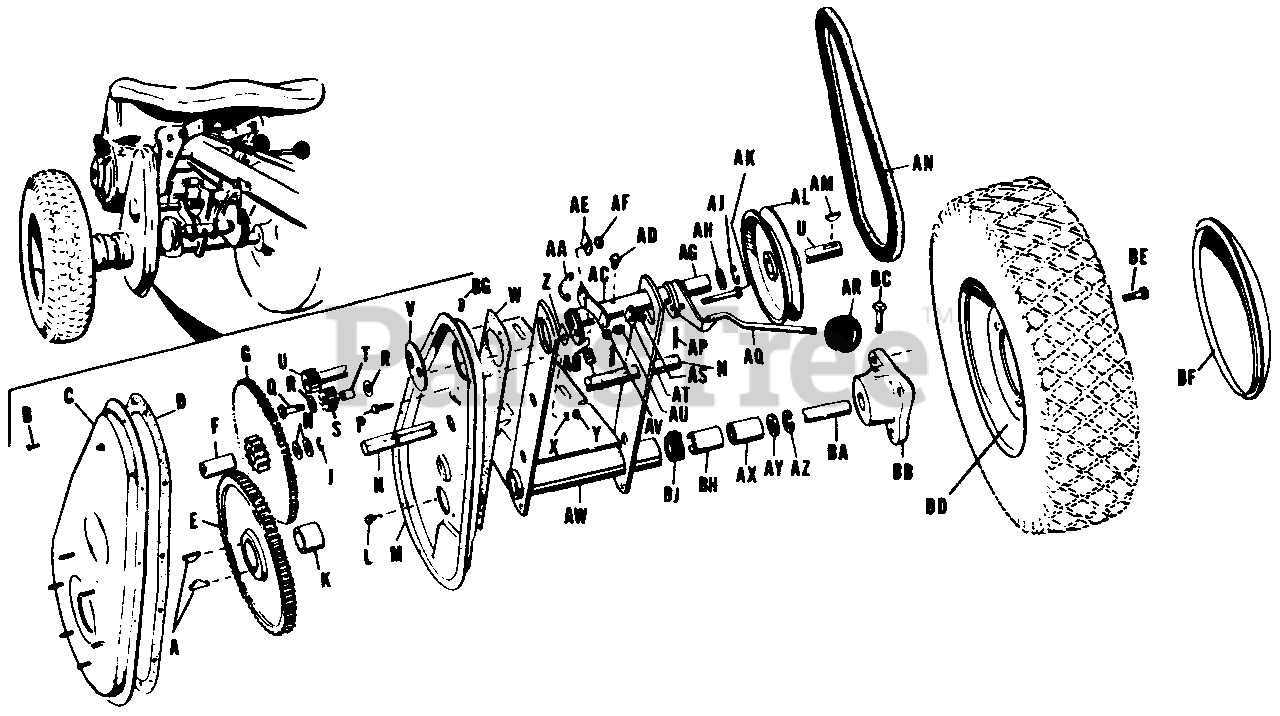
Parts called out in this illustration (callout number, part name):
A	Key, Hi Pro HP-608
B	Screw, Self Tapping #10 x 3/8
C	Cover Assembly, Gear Case
D	Gasket Gear Case
E	Gear, Drive
F	Bearing, Intermediate Pinion
G	Gear Assembly
J	Ring, retaining
L	Capscrew, 5/16-18 x 3/8
M	Case, Gear
N	Shaft, Intermediate
P	Capscrew, Hex Hd., 3/8-16 x 1
Q	Hex Hd., Bolt
R	Washer, Plain, 5/16
S	Pinion, Reverse
T	Spacer, Pinion
U	Pinion & Pulley Shaft
W	Gasket, Bearing Housing
X	Washer, Lock, 3/8
Y	Nut, Full Hex, 3/8-16
AA	Spring, Extension
AB	Spring, Reverse Lever
AC	Housing Assembly, Bearing
AD	Grease Fitting, Alemite # 1911
AE	Plate, Lock
AF	Nut, Full Hex
AJ	Ring, Retaining
AK	Capscrew, Hex Hd., 5/16-18 x 1
AL	Pulley, Transmission
AM	Key, Woodrulf, 3/16 x 3/4
AP	Pin, Cotter 3/16 x 1 1/4
AQ	Lever Assembly, Shift
AS	Nut, Hex Jam, 3/8-16
AT	Plate, Friction
AV	Nut, Lock, 3/8-16
AW	Housing Assembly, Axle
AX	Bearing, Axle
AZ	Ring, Retaining
BA	Axle, Rear
BB	Hub, Wheel, L.H.
BC	Screw, Set, Sq. Hd., 3/8-16 x 1 1/4
BD	Wheel, less tire & tube
BF	Hub Cap, Rear
BG	Speed Nut
BH	Cover, Axle House
